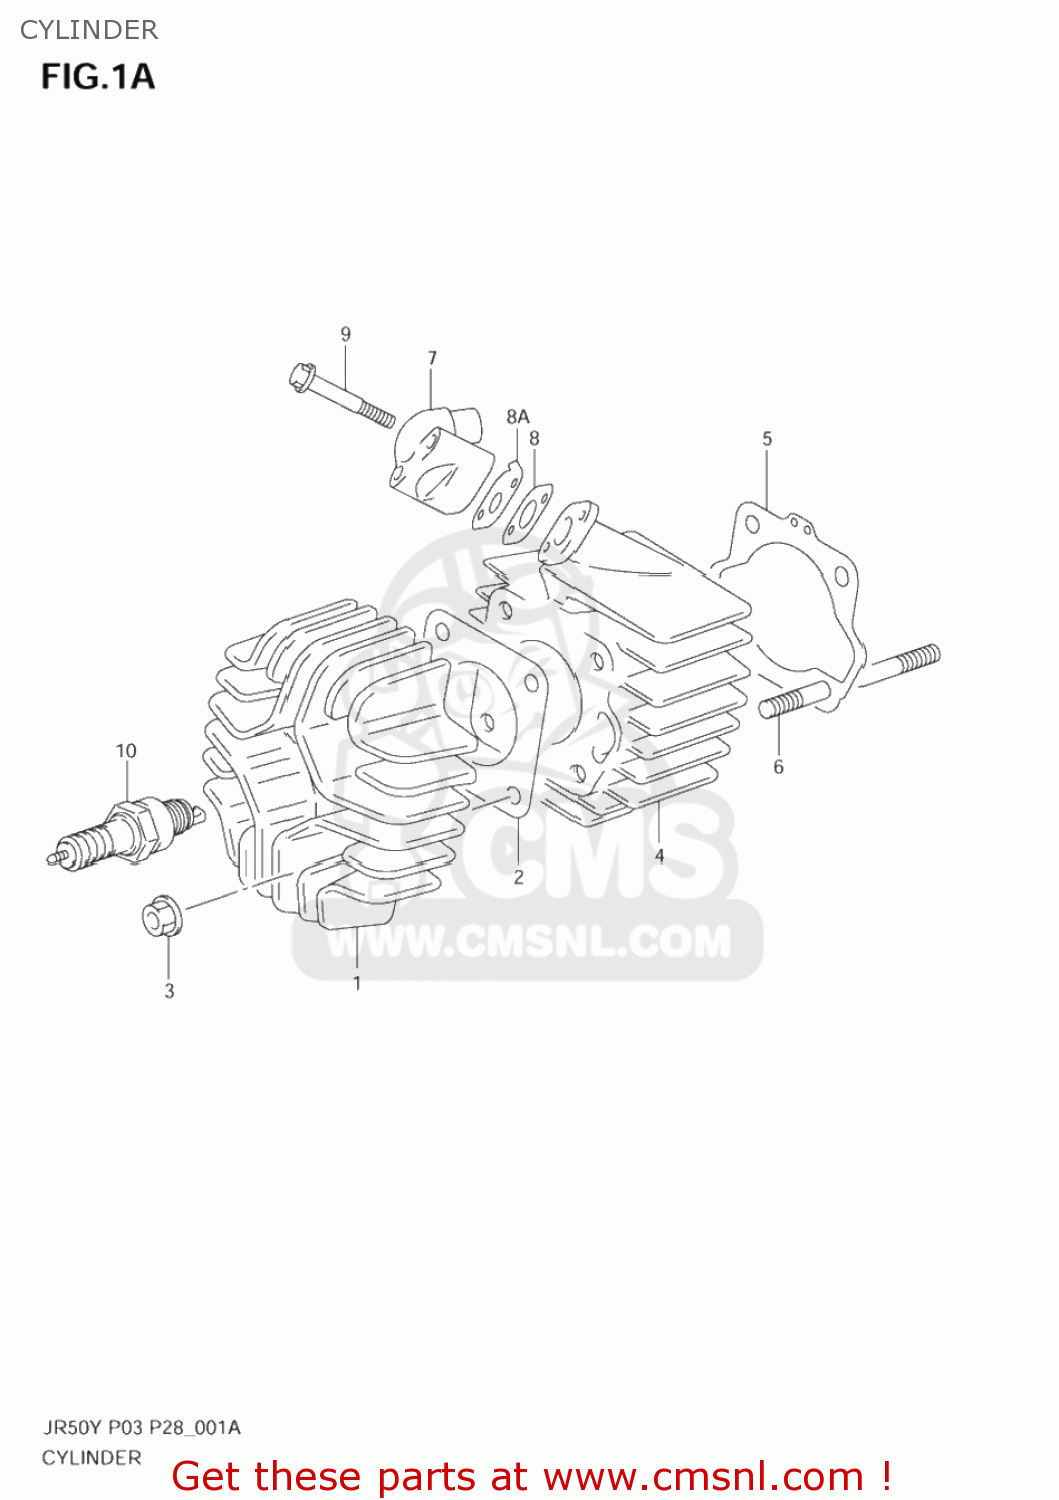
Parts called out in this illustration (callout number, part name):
1	HEAD,CYLINDER
2	GASKET,CYLINDER HEAD (NAS)
3	NUT
4	CYLINDER
5	GASKET,CYLINDER (NAS)
6	BOLT,STUD
7	PIPE,INTAKE
8	GASKET,INTAKE PIPE (NAS)
8A	GASKET,INTAKE PIPE NO.2 (NAS)
9	BOLT
10	SPARK PLUG W14FPR-UL
